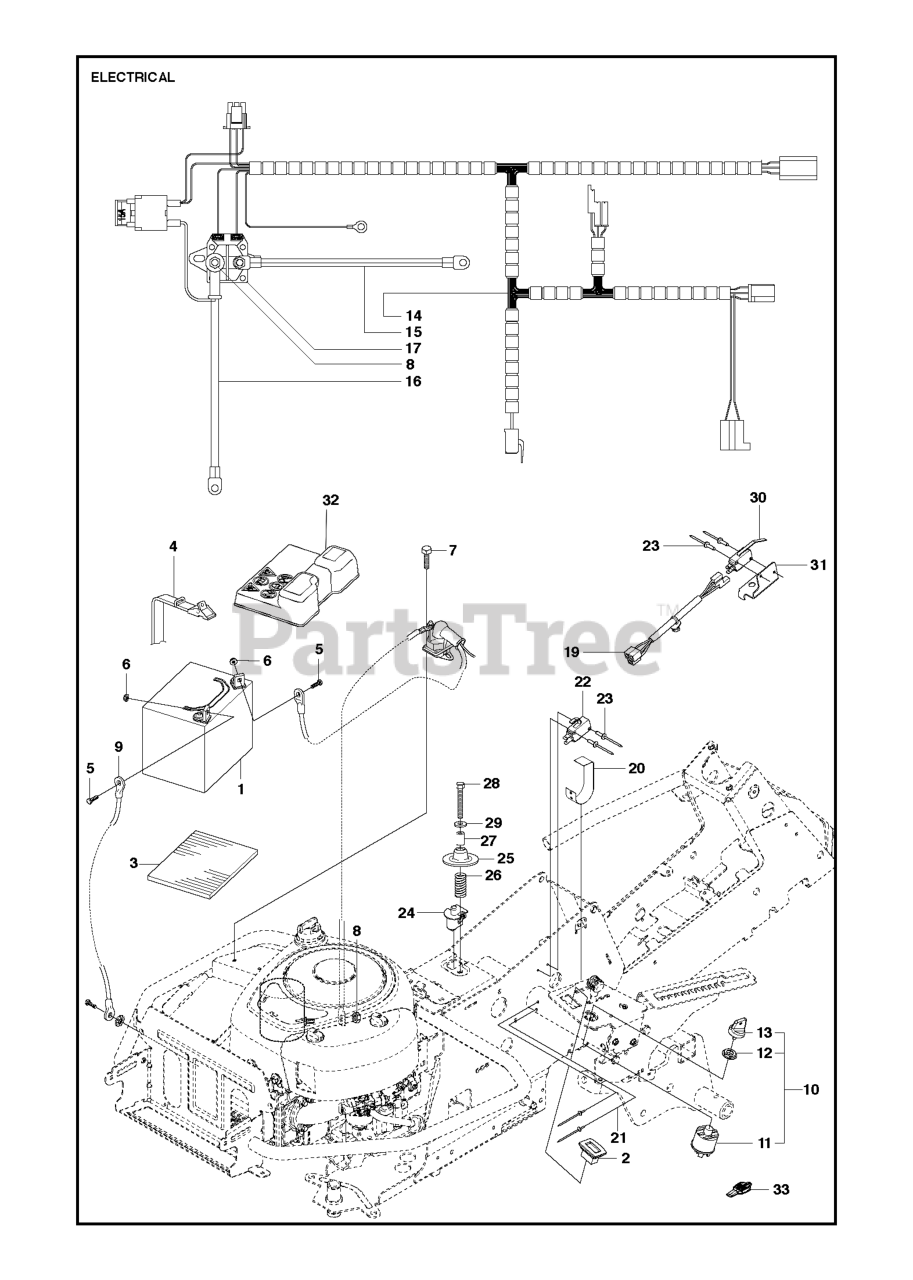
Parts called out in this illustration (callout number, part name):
2	HOUR METER
3	MAT
5	SCREW EHHM
10	IGNITION SWITCH
11	IGNITION SWITCH
13	IGNITION KEY
14	WIRING
16	WIRE BATTERY
19	WIRING
20	SPRING
21	Rivet
22	MICRO SWITCH
22	SWITCH
27	SPACER TUBE
28	SCREW
29	WASHER BRB 8.4X17
30	MICRO SWITCH
32	COVER
